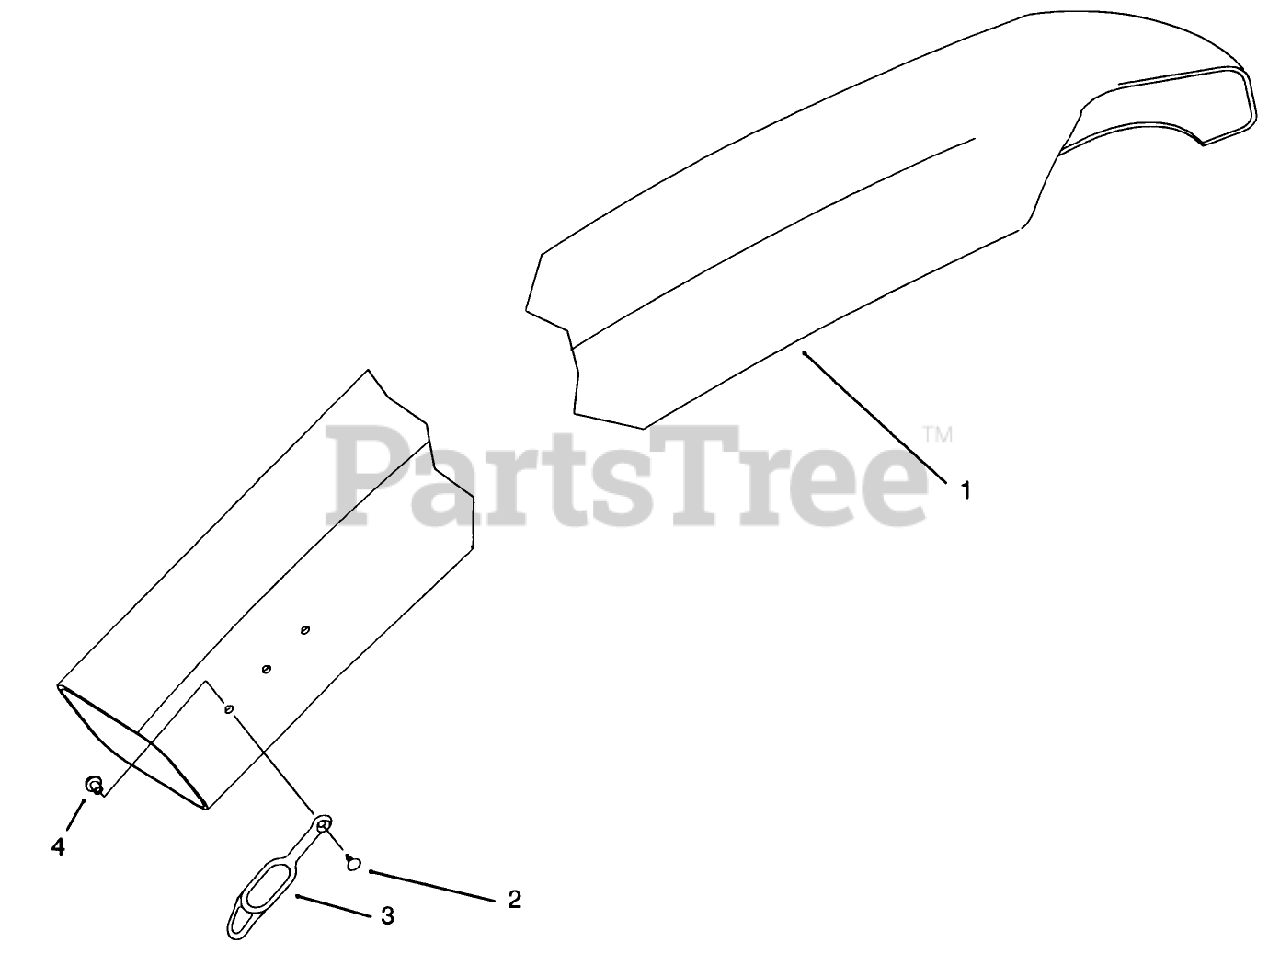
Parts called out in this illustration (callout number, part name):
1	CHUTE-DISCHARGE
2	FASTENER-PANEL
3	RETAINER-DUCT
4	SPACER-INTERLOCK
